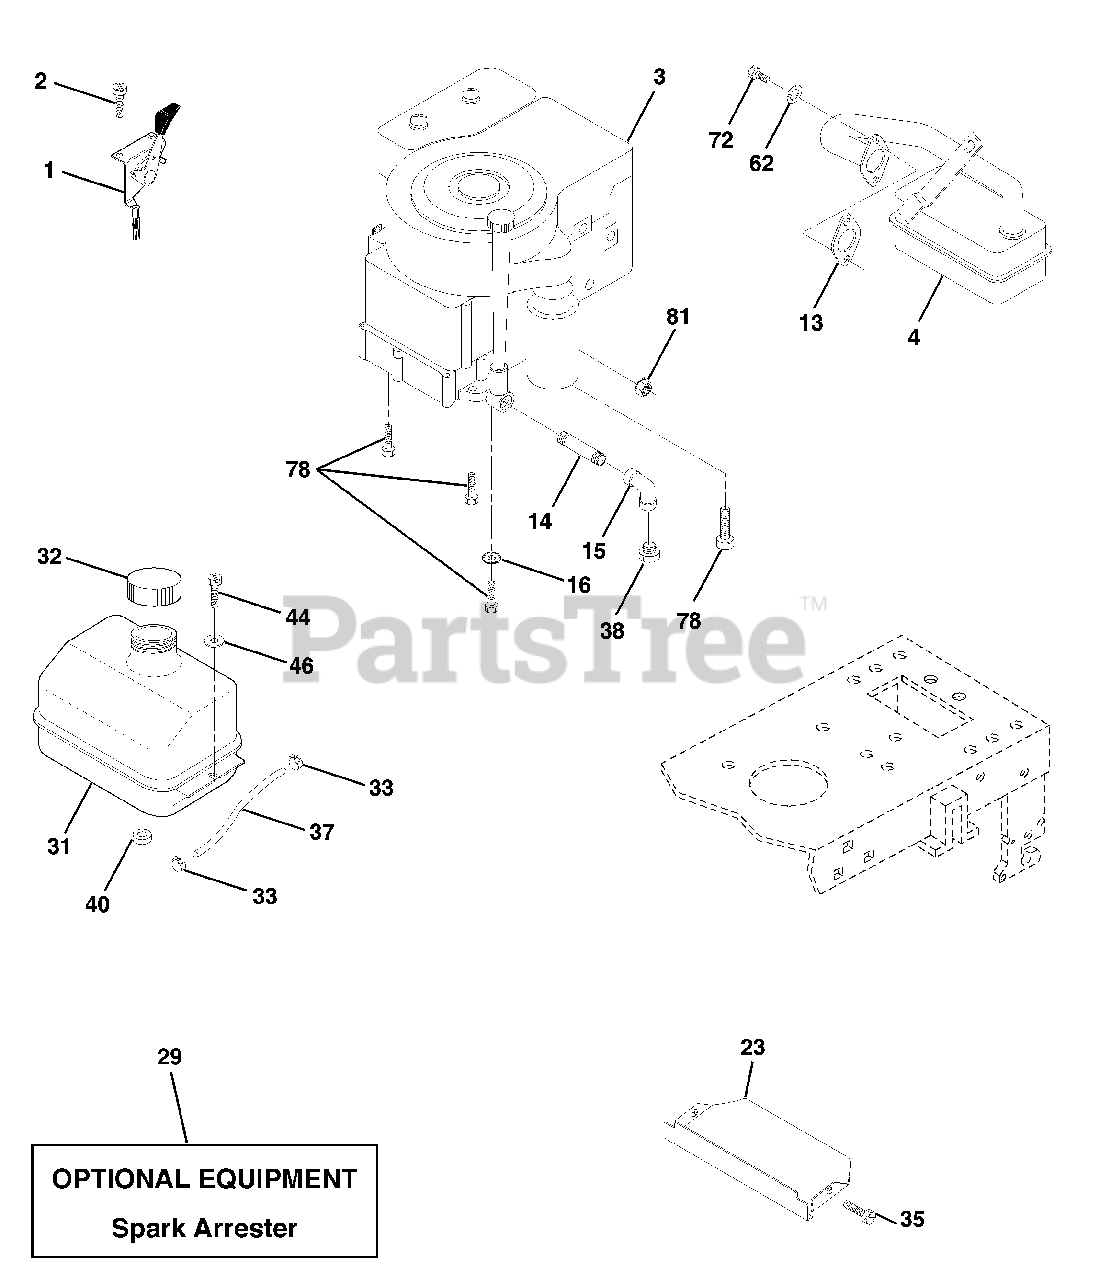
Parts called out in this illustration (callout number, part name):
1	Control Th/ch Flag
2	Screw Hex Thd Cut 1/4-20x5/8 T
4	Muffler Exhaust B&S Lc
13	Gasket Eng 1 313 Id Tin Plated
14	Nipple Pipe 3/8 Npt X 3"
15	Elbow Std 90 Degree 3/8-18 Npt
16	Washer Lock Ext Tooth 3/8
23	Shield Browning/Debris Guard
29	Kit Spark Arrestor (Flat Scrn)
31	Tank Fuel Front
32	Cap Asm Fuel
33	Clamp Hose
35	Screw Thdrol 5/16-18 x 3/4
37	Line Fuel 20"
38	Oil Drain Plug
40	Bushing Snap Nyl Blk Fuel Line
44	Screw Thdrol 1/4-20 x 3/4
46	Washer 9/32 X 7/8 X 16 Ga
62	Washer Lock Hvy Hlcl Spr
72	Screw Hex Hd Cap 5/16-18 x 3/4
78	Screw Thdrol 3/8-16x1-1/4 TYTT
81	Nut Flange 1/4-20 Starter Nut
